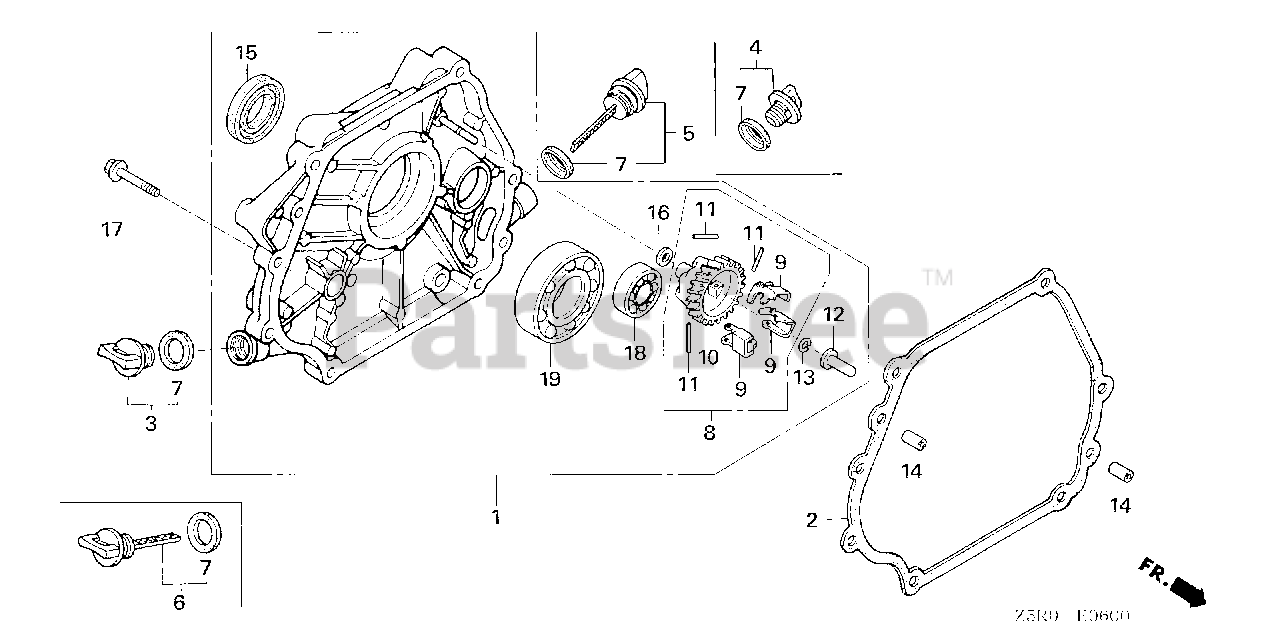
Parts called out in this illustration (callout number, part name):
1	COVER ASSY., CRANKCASE
2	GASKET, CASE COVER
3	CAP ASSY., OIL FILLER
5	CAP ASSY., OIL FILLER
7	GASKET, OIL FILLER CAP
8	GOVERNOR ASSY.
9	WEIGHT, GOVERNOR
10	HOLDER, GOVERNOR WEIGHT
11	PIN, GOVERNOR WEIGHT
12	SLIDER, GOVERNOR
13	CLIP, GOVERNOR HOLDER
14	PIN, DOWEL (8X12)
15	OIL SEAL (35X52X8)
16	WASHER, PLAIN (6MM)
17	BOLT, FLANGE (8X40)
18	BEARING, RADIAL BALL (6202)
19	BEARING, RADIAL BALL (6207)
